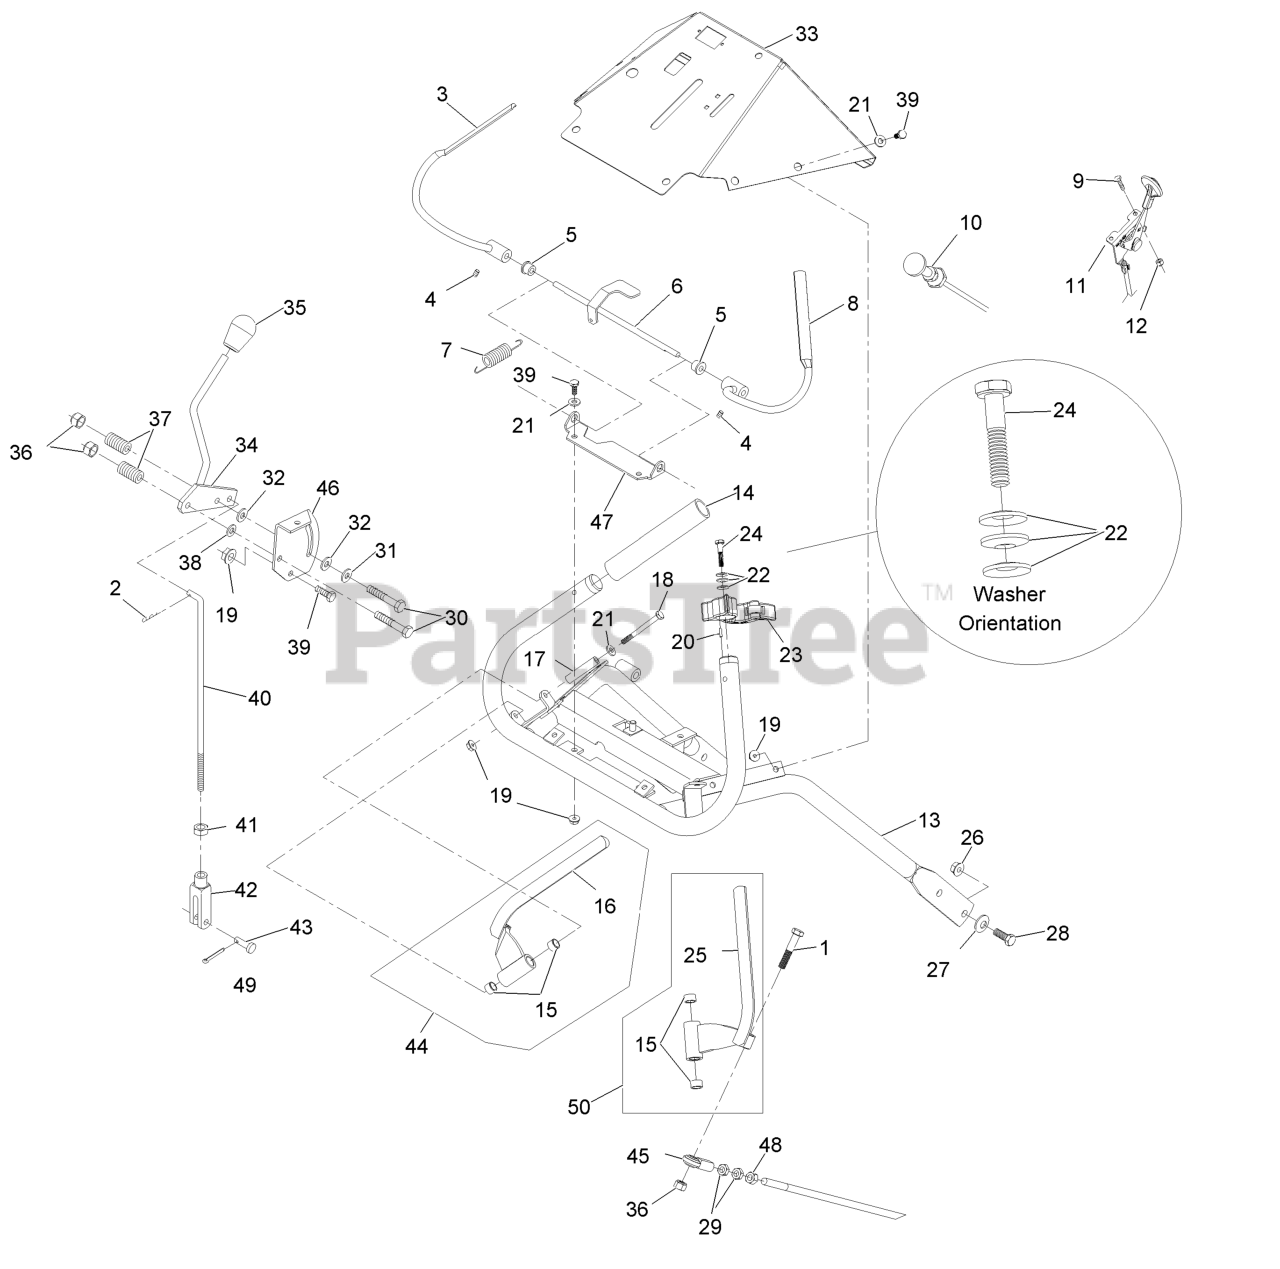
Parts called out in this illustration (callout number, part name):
1	SCREW-HH
2	PIN-COTTER
3	WLD,LH OPC LEVER
4	SCREW-SET
5	BUSHING-NYLON
6	WLD,OPC LEVER AXLE
7	SPRING-EXTENSION
8	WLD,RH OPC LEVER
9	BOLT-CARR
10	CONTROL-CHOKE, PUSH / PUL
11	CONTROL, THROTTLE
12	NUT-LOCK, NI
13	WLD,TTH ECS HANDLE
14	GRIP-BAR, HANDLE
15	BUSHING-SLEEVE
16	WLD,LH DRIVE LEVER
17	BUSHING-LEVER, DRIVE
18	SCREW-HH
21	WASHER-FLAT
22	WASHER-SPRING
23	ASM,LATCH RH THUMB
24	SCREW-HH
25	WLD,RH DRIVE LEVER
26	NUT-HHF, WHIZ
27	WASHER-BELLEVILLE
28	SCREW-HH
29	NUT-HJ
30	SCREW-HH
31	WASHER-FRICTION
32	WASHER-FRICTION
33	Console 116-3387-03 W/Decals
35	KNOB, FE.LCKG. BLACK
36	NUT-LOCK, NI
37	SPRING-COMPRESSION
38	WASHER-PLAIN
39	SCREW-HH
40	ROD,SPEED CONTROL
41	NUT-JAM
42	YOKE-ADJUSTABLE
43	PIN-CLEVIS
44	DRIVE LEVER-ASM, RH
45	JOINT-BALL, END
46	BRACKET,SHIFTER SLIDE (PL
47	BRACKET,OPC AXLE
48	NUT-HEX
49	PIN-COTTER
50	DRIVE LEVER-ASM, LH
